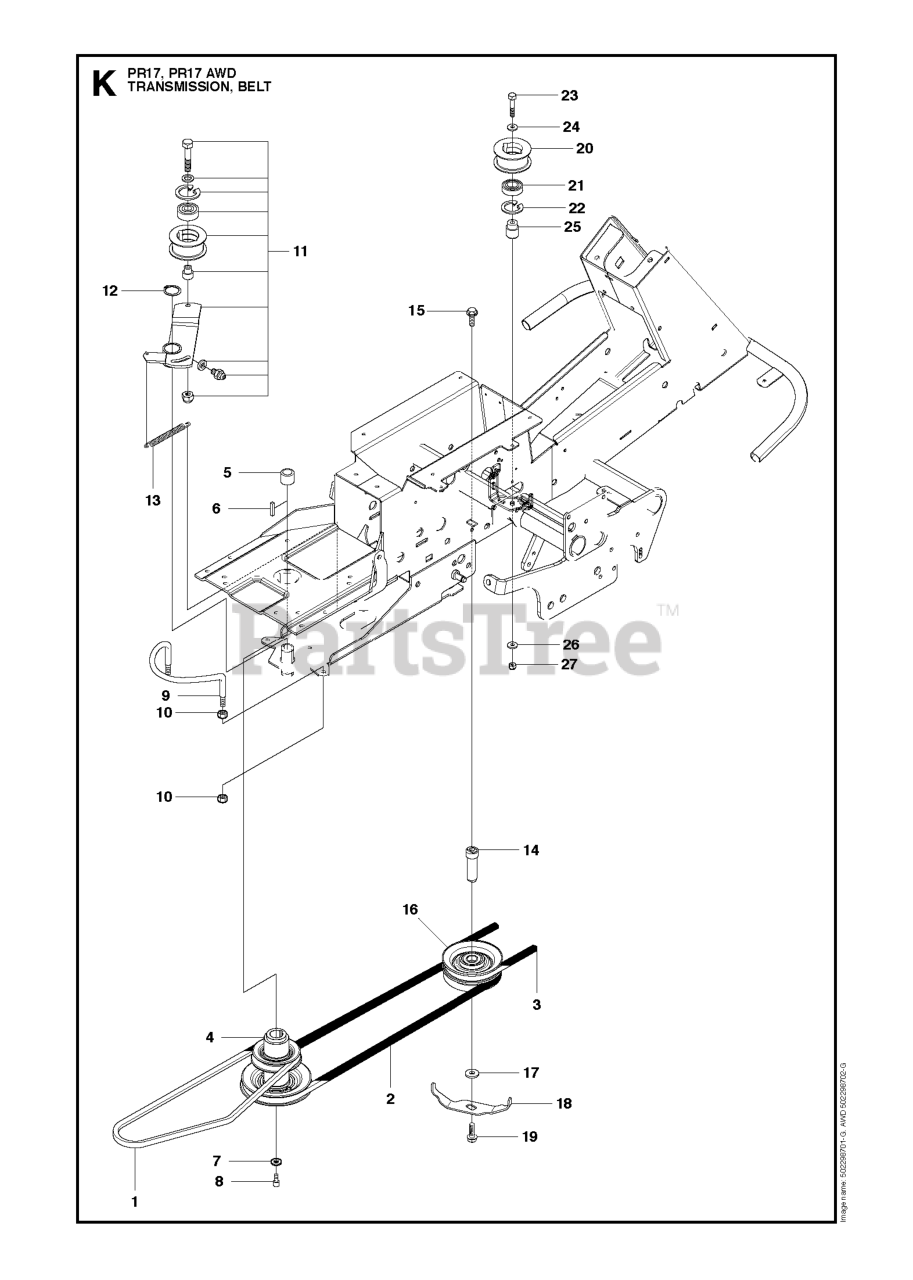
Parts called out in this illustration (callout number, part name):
1	BELT
3	BELT
9	BELT GUIDE
10	NUT
12	RETAINING RING SGA 25
18	BELT GUIDE
19	BOLT
20	%PULLEY
21	BALL BEARING 6004-2RS1
22	RETAINING RING
26	WASHER BRB 8.4X17
27	LOCKNUT M8
